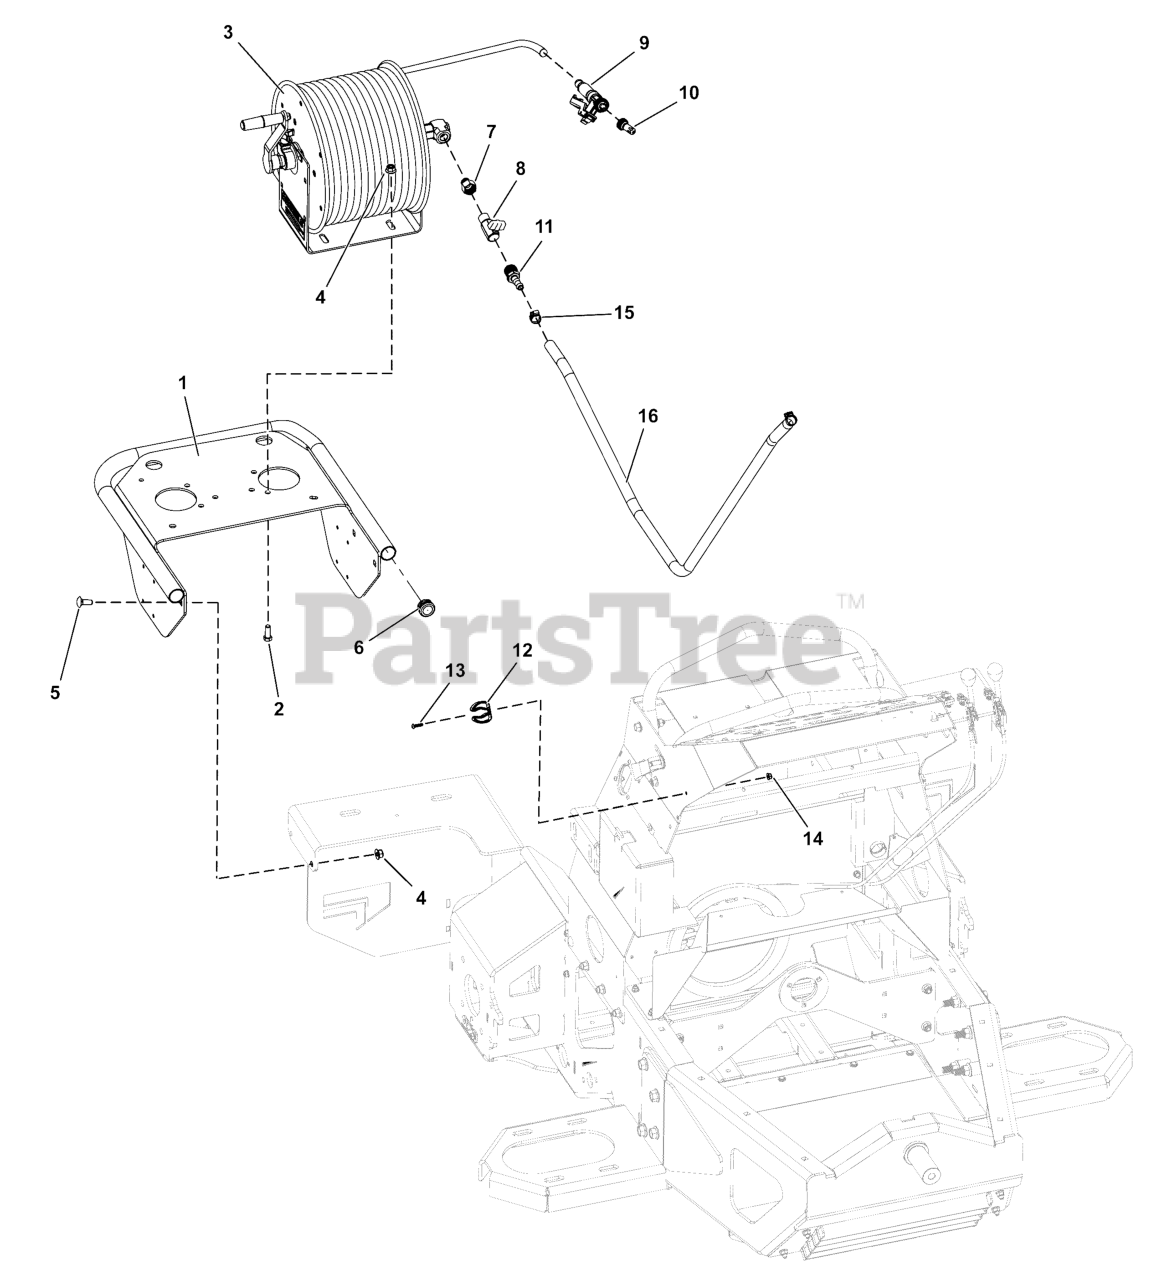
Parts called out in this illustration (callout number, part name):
1	WELD, ACCESSORY MOUNT
2	SCR-CAP, HEX .375"-16 X 1.000" SS188
3	REEL,SPOT SPRAY HOSE 75 FT.
4	NUT-HEX-NYLK, FLG .375"-16 SS188
5	BLT-RDHDSQNK, .375"-16 X 1.000" SS188
6	PLUG TUBE INSERT 1.25" O.D.
7	FTG, STR 3/8" MNPT - 1/2" FNPT BRASS
8	VALVE, BALL, 1/2 MPT - 1/2 FPT
9	SPRAY GUN, 1/4 FPT
10	NOZZLE TIP, ADJUSTABLE SPRAY, STANDARD
11	FTG, STR 1/2" MNPT - 1/2" HB BPP
12	CLIP, .750" O.D. OIL DRAIN HOSE
13	SCR-CAP, SBH #10-24 X .750" SS188
14	NUT-HEX-NYLK, FLG .#10-24 SS188
15	CLAMP, MINIATURE WORM GEAR MAH6
16	HOSE, CHEM .50" X 64"
